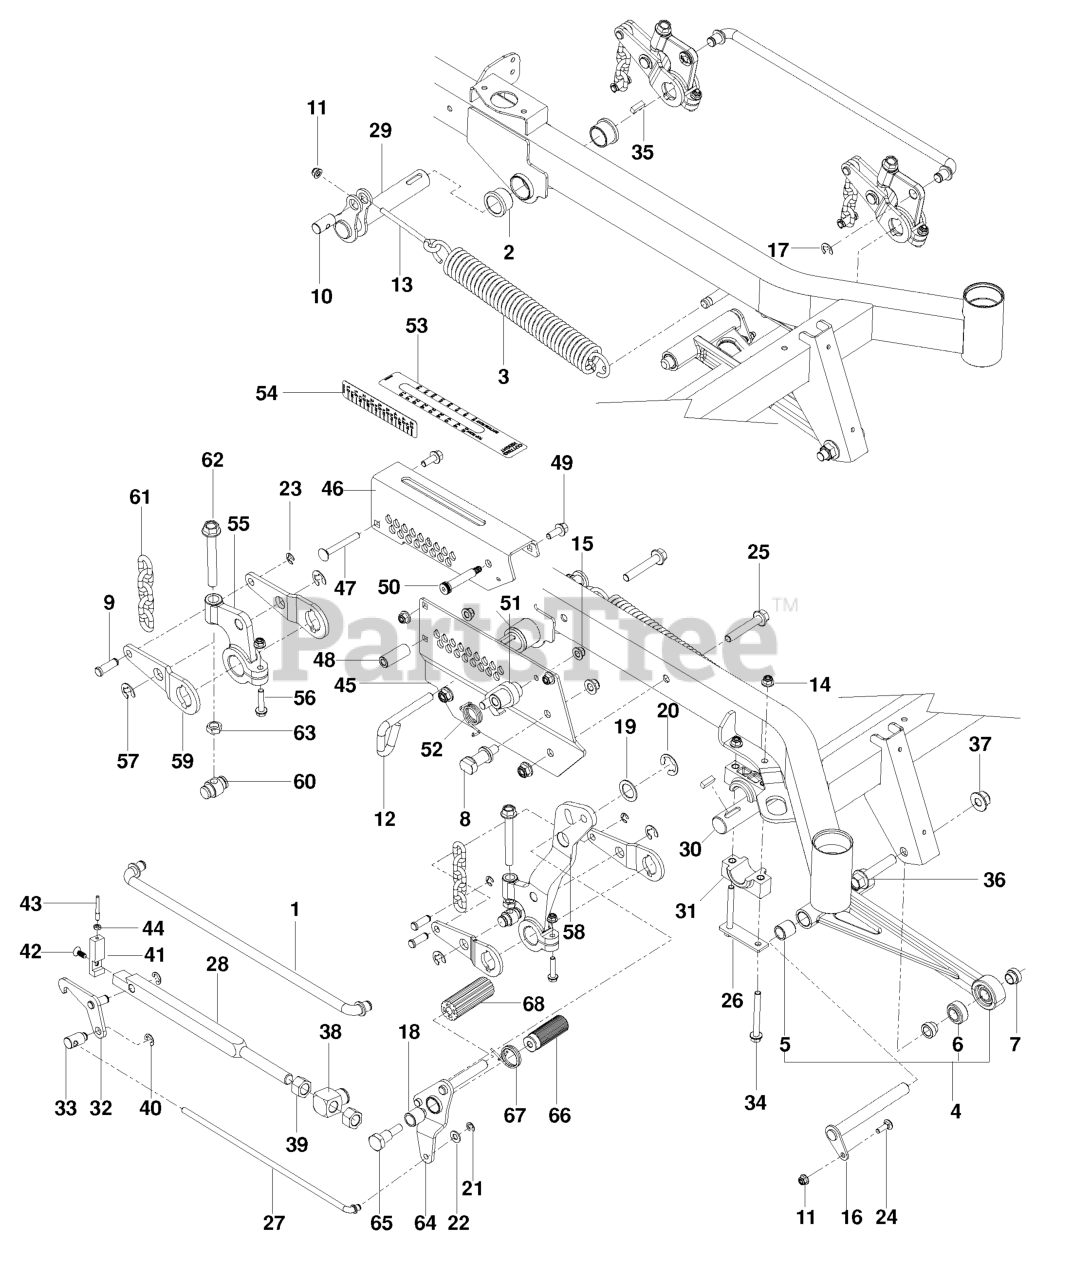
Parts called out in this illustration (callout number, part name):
1	ROD, LIFT
2	BUSHING, FLANGE 1.25 X 1.0
3	SPRING, EXTENSION
4	ASSEMBLY, STRUT
5	BUSHING, SLEEVE 3/4 X 1.0
6	BALL JOINT, 3/4" SWIVEL
7	SPACER, STRUT
8	GUIDE, HEIGHT BAR
9	PIN, 7/16 CLEVIS
10	PIVOT, SPRING
11	5/16-18 NYLOC FLANGE NUT
12	PIN, HEIGHT
13	EYE BOLT 4.5`
14	NUT 3/8-16 HEX FLG NYLOC ZD
15	NUT, 1/2-13 HEX FLG NYLOC ZD
16	PIN, STRUT
17	E-RING 5/8
18	BUSHING, SLEEVE 3/4 X 1.0
19	MACHINE BUSHING
20	E-RING 1"
21	E RING 3/8"
22	WASHER 3/8 SAE FLAT
23	RING, E, 7/16
24	RHSNB 5/16C X 1
25	HFFS 1/2-13 X 3 GD 5 ZD
26	PLATE, PILLOW BLACK
27	ROD, HEIGHT LATCH
28	BAR, HEIGHT
29	SHAFT, RR LIFT
30	SHAFT, LIFT, FT
31	BLOCK, PILLOW
32	LATCH, HEIGHT WLDMT
33	SWIVEL, HEIGHT LATCH
34	HHFS 3/8-16 X 3.5 GD 5 ZD
35	KEY, 5/16 SQ X 1.0
36	HHFS 5/8-11 X 3.0 GD 8 ZD
37	NUT 5/8-11 FLG NYLOC ZD
38	SWIVEL, HEIGHT BAR
39	NUT 3/4-10 HEX ZD
40	E-RING 1/2 (2 2)
41	CAP, HEIGHT BAR
42	SCREW, 5/16-18 X 3/4 FLAT HEX
43	LINK, INDICATOR
44	NUT 1/4-20 JAM
45	PLATE, INNER HEIGHT, ORANGE
46	PLATE, OUTER HEIGHT ORG
47	3/8-16 X 3` CARR BOLT
48	SPACER, HEIGHT PLATE
49	HHFS 3/8-16 X 1 GRD 5 ZD
50	BOLT, SHOULDER, 1/2 X 2.25
51	LATCH, TRANSPORT WLDMT
52	SPRING, TORSION
53	DECAL, HEIGHT
54	DECAL, HEIGHT
55	ARM, CAST LIFT
56	HHFS 5/16-18 X 1.5 GD 5
57	E RING 3/4
58	ARM, LIFT LEVER
59	ARM LIFT BLK
60	SHAFT, LIFT TRUNION WSL
61	LIFT CHAIN
62	HHFS 1/2-13 X 4 GR 5
63	NUT 1/2 HEX JAM
64	PEDAL, RELEASE WLDMT
65	BOLT, SHOULDER
66	PAD, FOOT PEDAL
67	SPRING, TORSION
68	PEDAL, DECK HEIGHT
